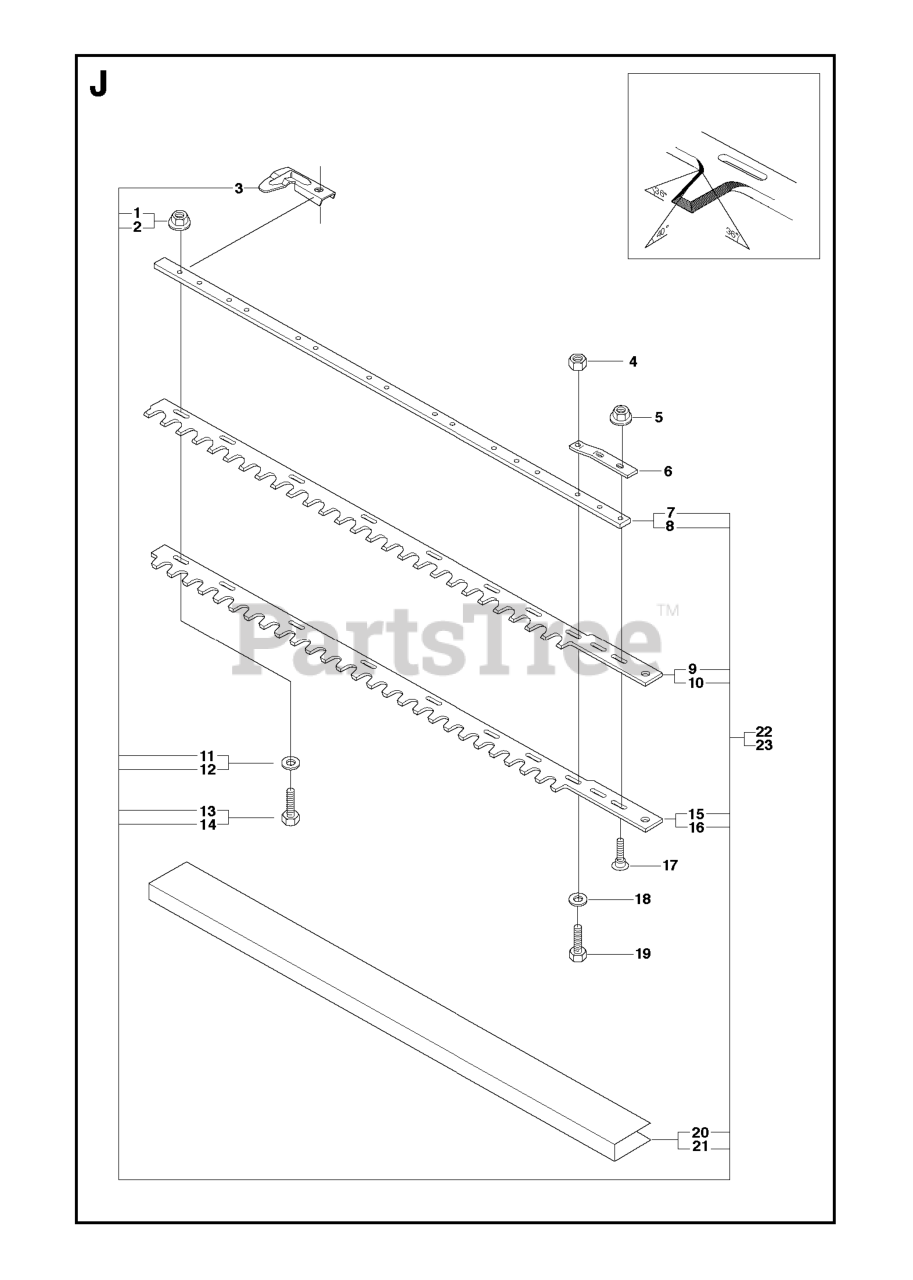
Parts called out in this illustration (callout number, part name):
5	NUT
7	BAR
8	BAR
9	BLADE
10	BLADE
11	WASHER 6,4X18X1,5
12	WASHER 6,4X18X1,5
15	BLADE
16	BLADE
18	WASHER 6,4X18X1,5
20	COVER
21	COVER
22	CUTTER ASSY
23	CUTTER ASSY
